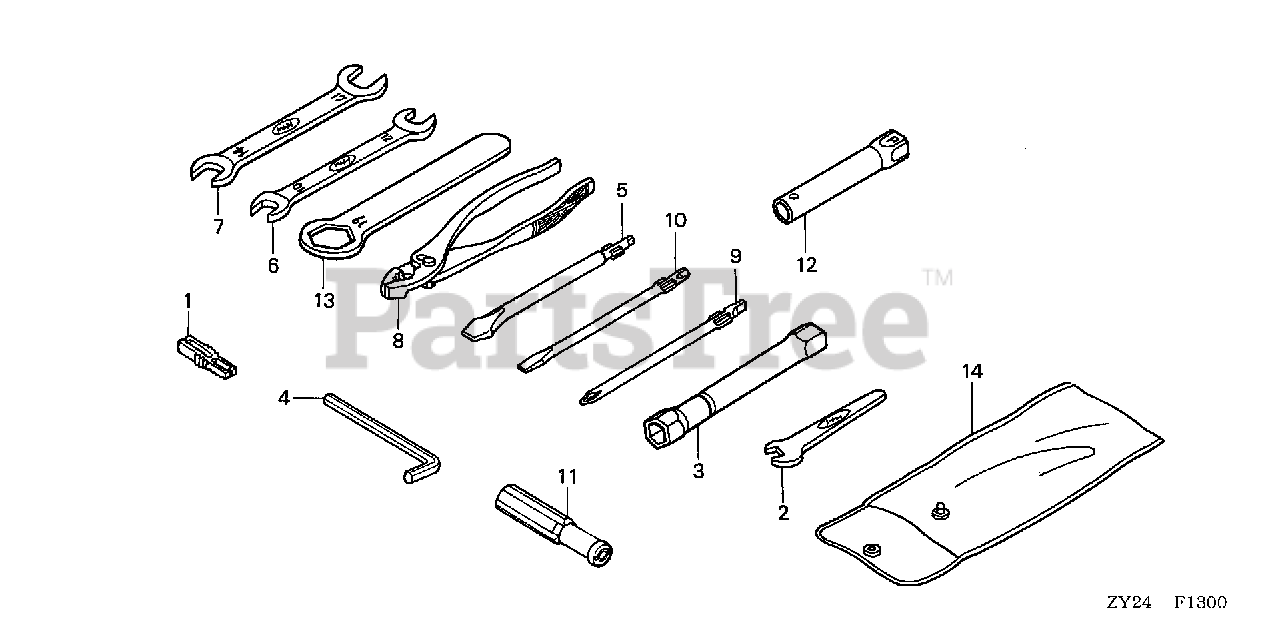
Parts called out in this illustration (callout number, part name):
1	PULLER, MINI FUSE (SUMITOMO)
2	SPANNER (8MM) (NOT AVAILABLE)
3	WRENCH, PLUG
4	WRENCH, HEX. (6MM)
5	SCREWDRIVER, CHECK BOLT
6	SPANNER (10X12)
7	SPANNER (14X17)
8	PLIERS (135) (KOWA)
8	PLIERS (135)
9	DRIVER 1, PLUS SCREW (NO.2)
10	DRIVER 3, MINUS SCREW (NO.2)
11	GRIP, SCREW DRIVER
12	WRENCH, BOX (P16X17)
13	WRENCH, EYE (19MM)
